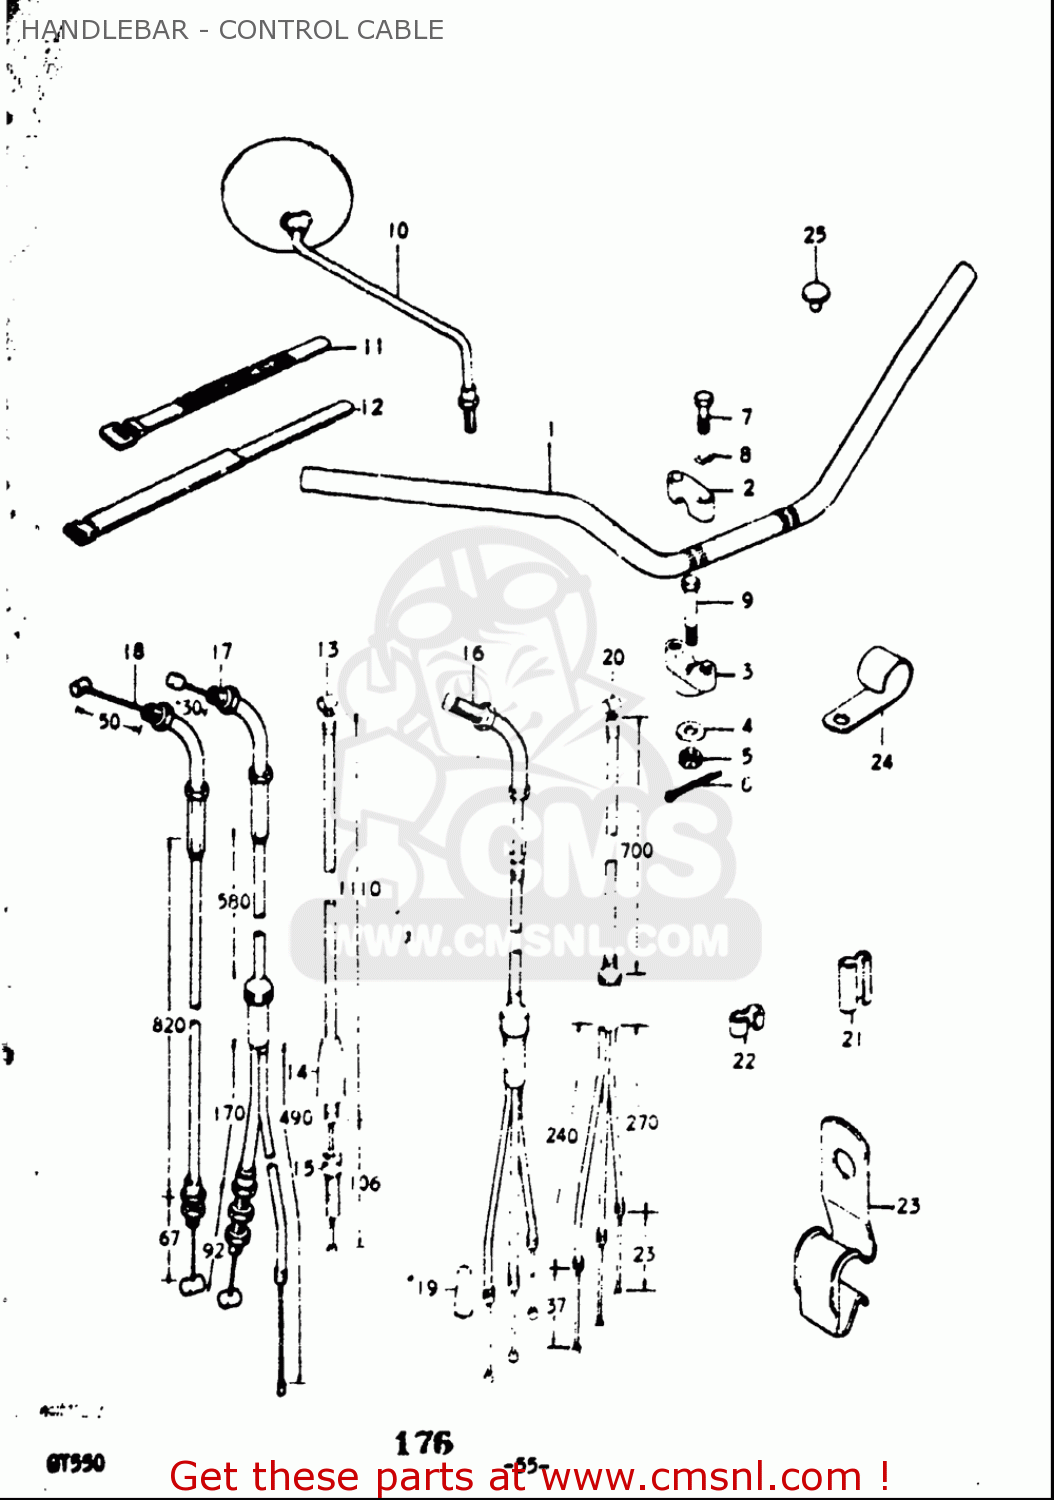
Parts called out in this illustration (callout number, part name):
1	HANDLEBAR
2	HOLDER,HANDLE UPR
3	HOLDER,HANDLEBAR LWR
4	WASHER(10.5X28X2.3)
5	NUT
6	PIN, COTTER
7	BOLT
8	WASHER,LOCK
10	MIRROR ASSY,RE
11	CLAMP(L:120)
12	CLAMP(L:250)
13	WIRE,CLUTCH
15	NUT
16	CABLE ASSY,THROTTLE
17	CABLE ASSY,THROTTLE NO.1
18	CABLE ASSY,THROTTLE NO.2
19	SEAL,DUST(7X18X30)
21	CLIP
22	CLIP
23	GUIDE,CABLE
24	CLIP
